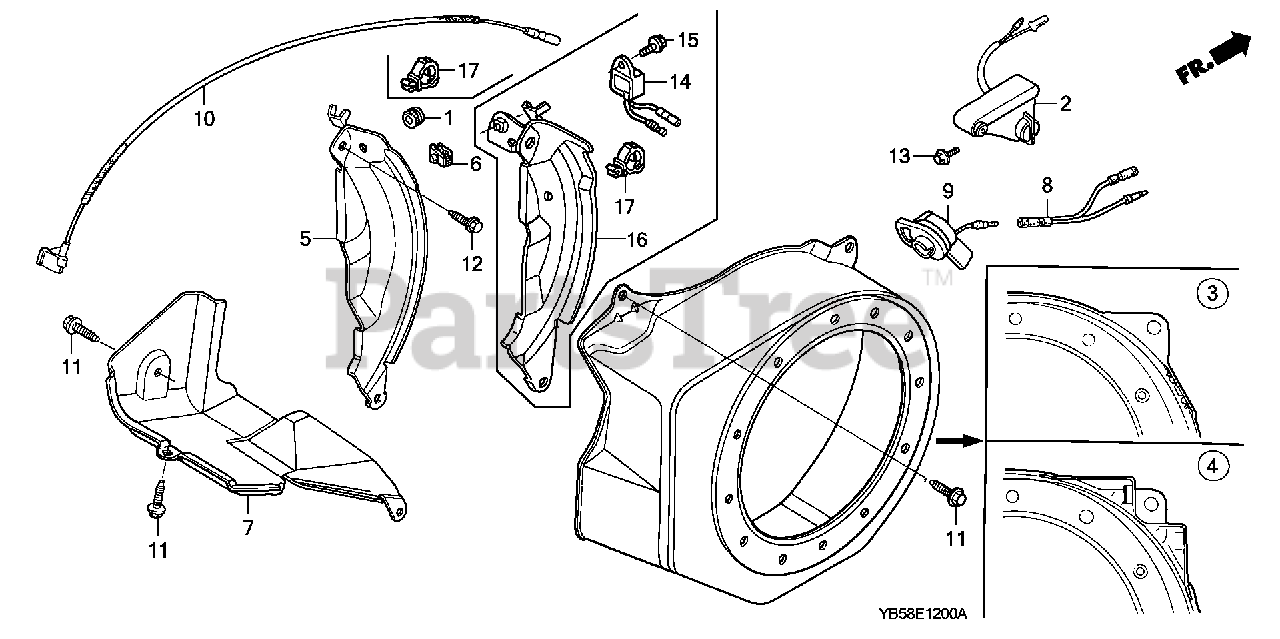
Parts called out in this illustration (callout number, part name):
3	COVER, FAN *R280* (POWER RED)
5	PLATE, SIDE (OIL ALERT)
9	SWITCH ASSY., ENGINE STOP
10	WIRE, STOP SWITCH (370MM)
11	BOLT, FLANGE (6X12) (CT200)
12	BOLT, FLANGE (6X20) (CT200)
14	ALERT UNIT, OIL
15	BOLT, FLANGE (6X8)
16	PLATE, SIDE (OIL ALERT)
17	CLIP, HARNESS
